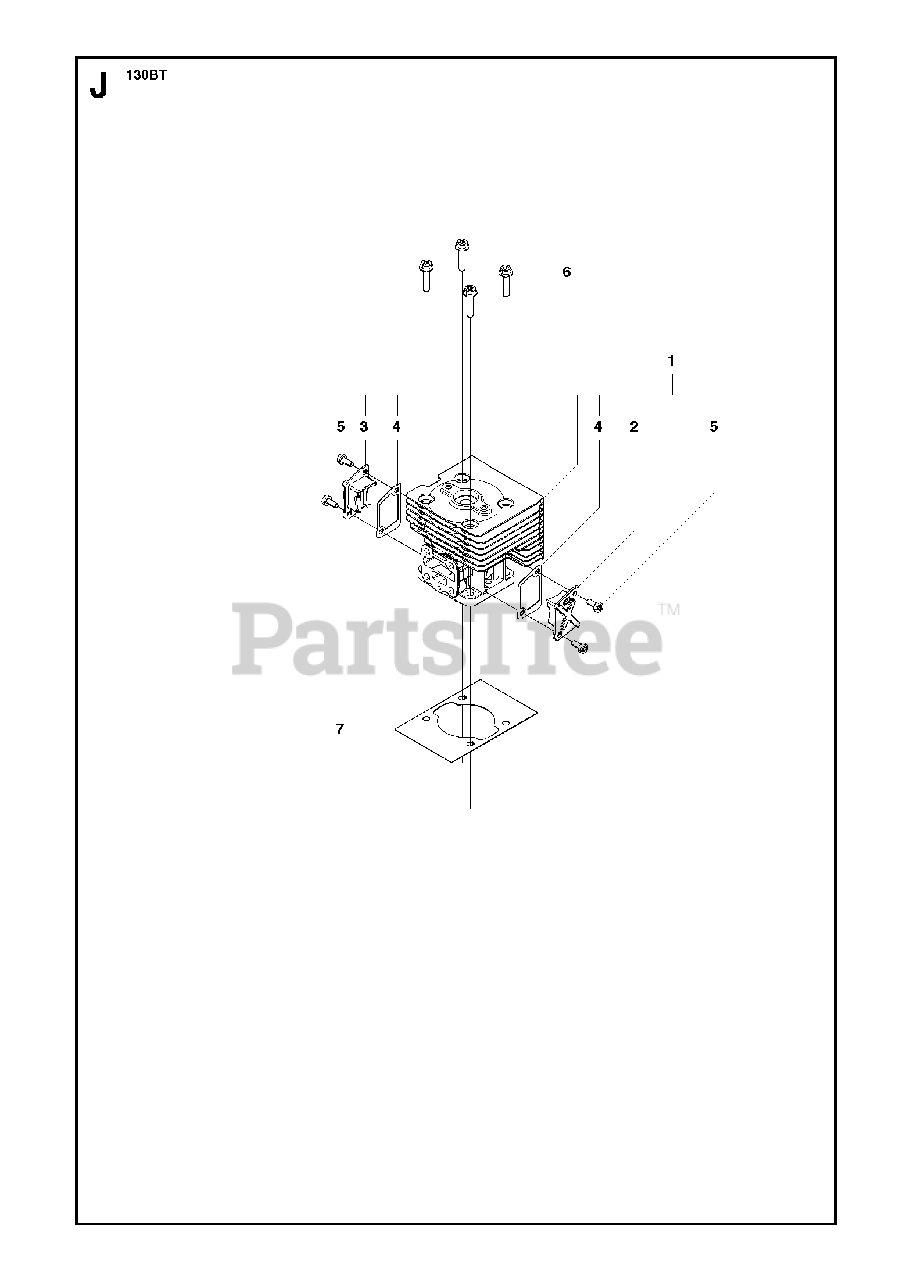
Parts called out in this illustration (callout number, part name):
1	CYLINDER
2	Cover
3	COVER TR (F)
4	GASKET TR
5	BOLT
7	GASKET BASE
